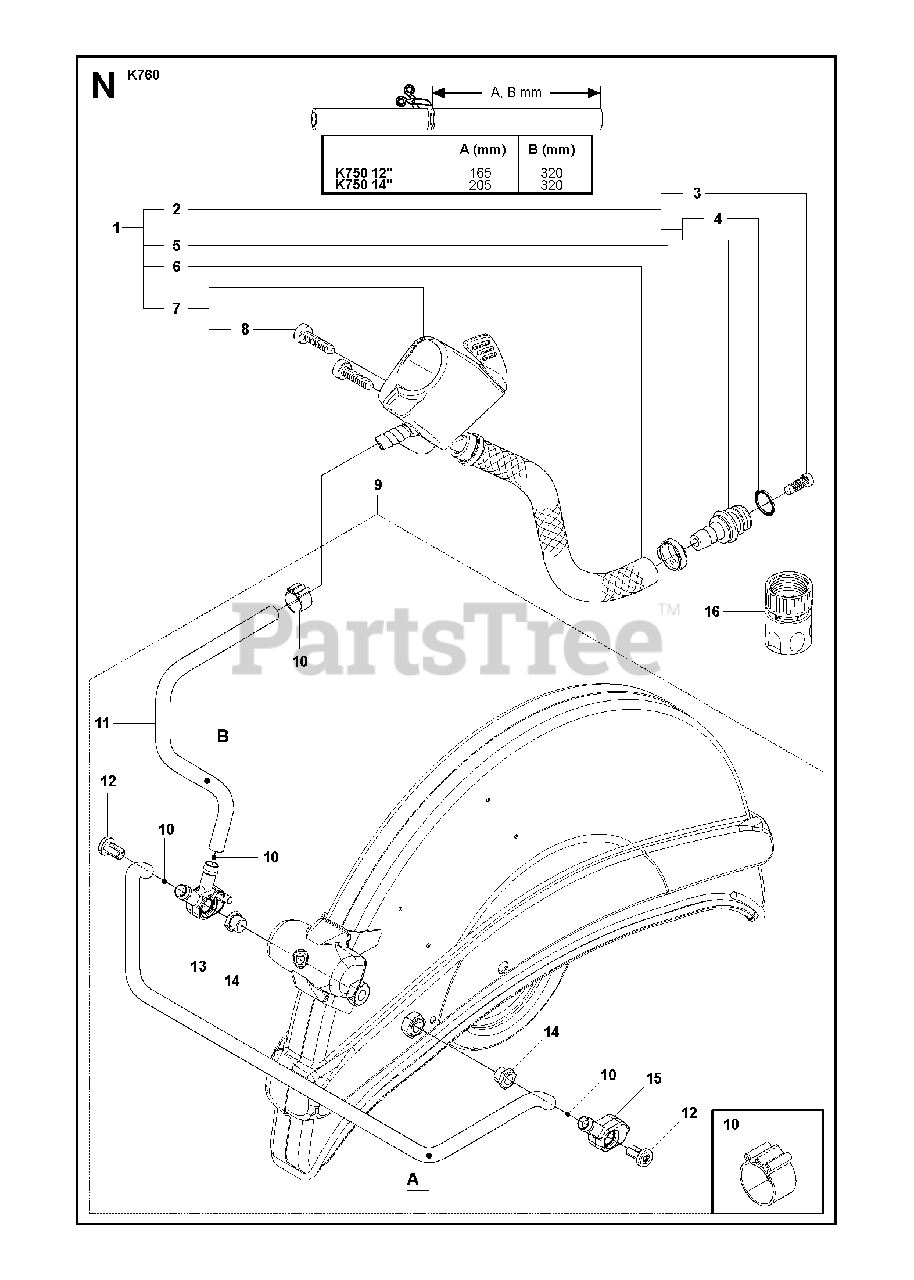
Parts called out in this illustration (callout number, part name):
1	HOSE KITIncl. 2, 5 - 7
2	NIPPLEIncl. 3, 4
5	HOSE CLAMP
7	VALVE ASSYIncl. 8
8	SCREW ITXSCT
9	HOSE KITIncl. 10 - 15
11	HOSE620 mm
12	SCREW ITXSCM
16	COUPLERUSA, Canada
